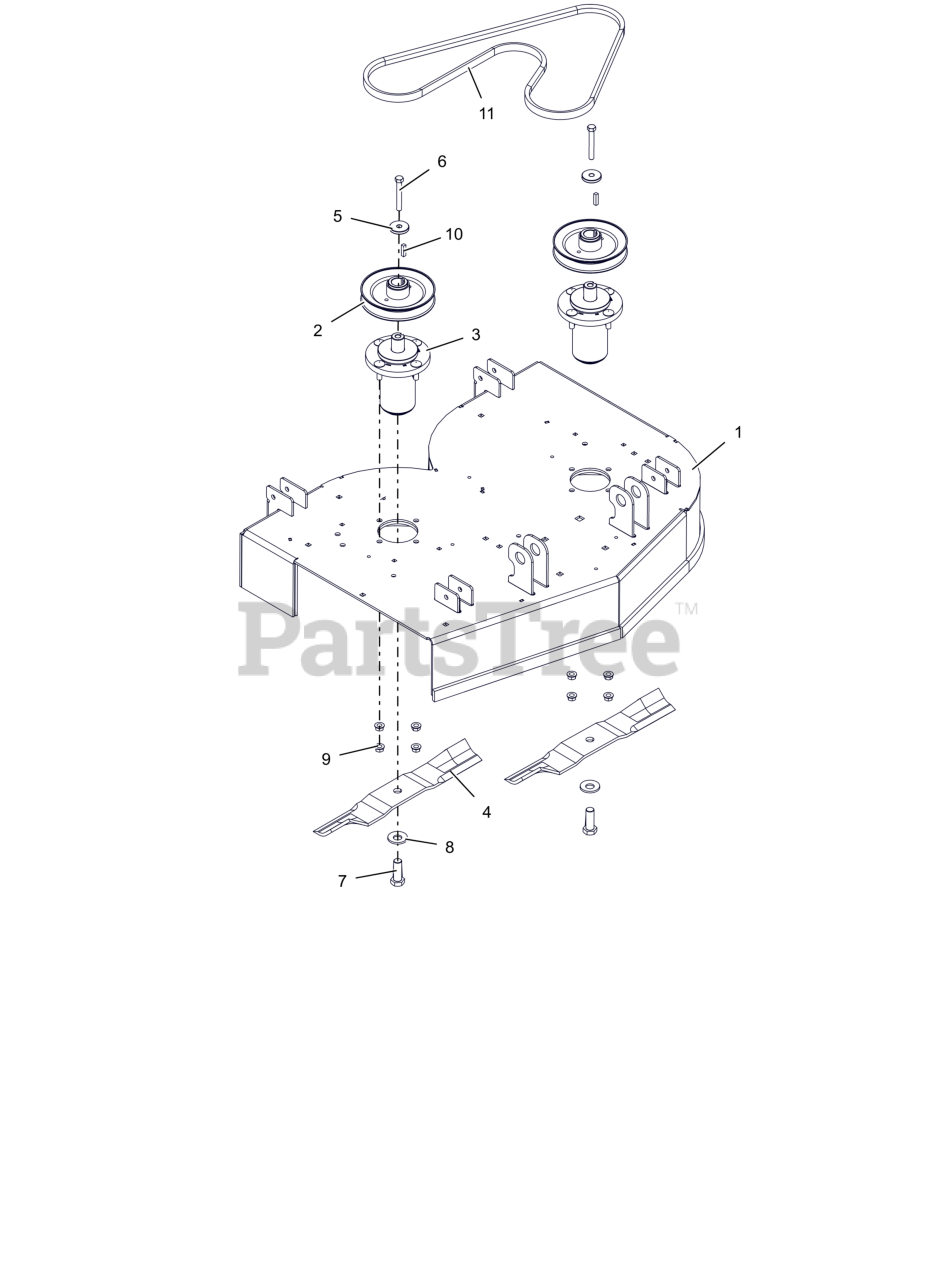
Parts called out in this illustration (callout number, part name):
1	WLDMT, 32" ARROW DECK (ORANGE)
2	PULLEY- V-1.000 ID X 5.750 OD
3	ASM, MAINT FREE ALUM SPINDLE
4	BLADE, 16.19" MOWER (HI-LIFT)
5	RETAINER, SHEAVE
6	BLT, HEX .38-16X2.75 G8 ZCC
7	BLT, HEX .62-18X1.75 G8 ZCC
8	WSHR-BLVL .669X1.535X.138
9	NUT-LK-CTR-FLG .375-16 GF ZCC
10	KEY, SQ .25X.25X1.00 RC 40-50
11	V-BELT, 5L RAW EDGE EPDM
